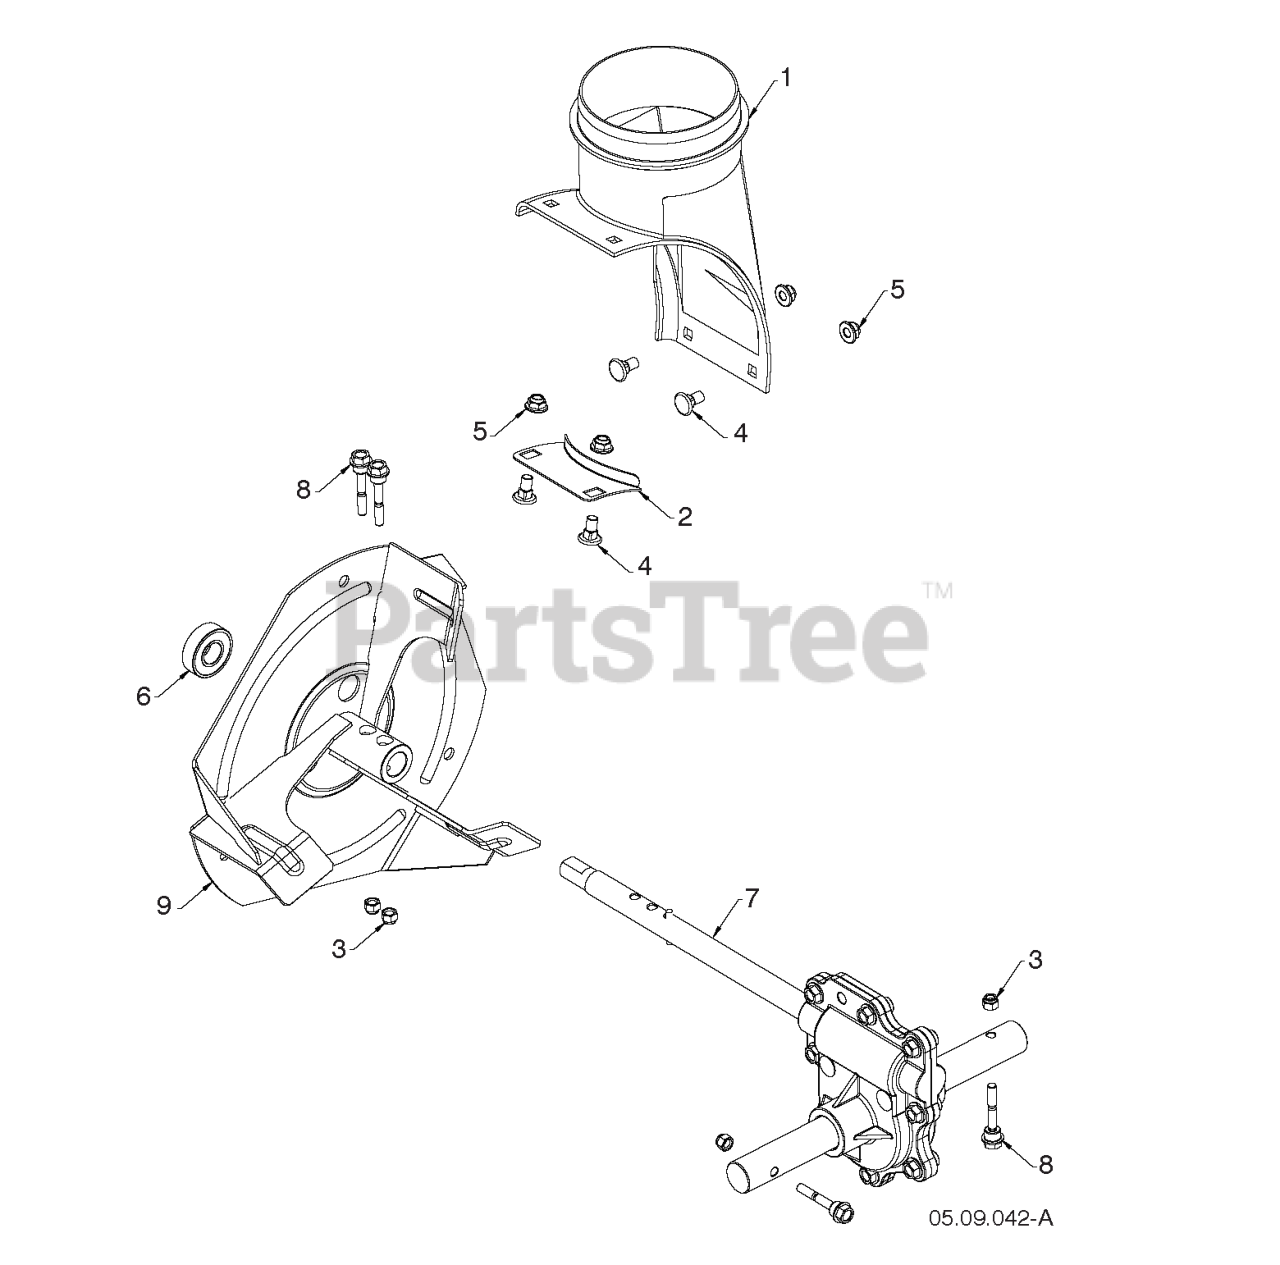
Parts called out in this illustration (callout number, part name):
1	CHUTE.DISCHARGE.BASE
2	BRACKET, CORNER DISCHARGE
3	Nut Lock, W/Insert 1/4 - 20 UNC (AYP part number)
4	BOLT CARR WAFER BLK 5_16-18 X
5	NUT HEX FLG NYLOCK BLK 5_16-1
7	GUIDE.LOWER.AUGER.BELT.479
8	BOLT.1/4-20 X 1-13/16 SHEAR
9	IMPELLER.STEEL.SNOW.BLACK
